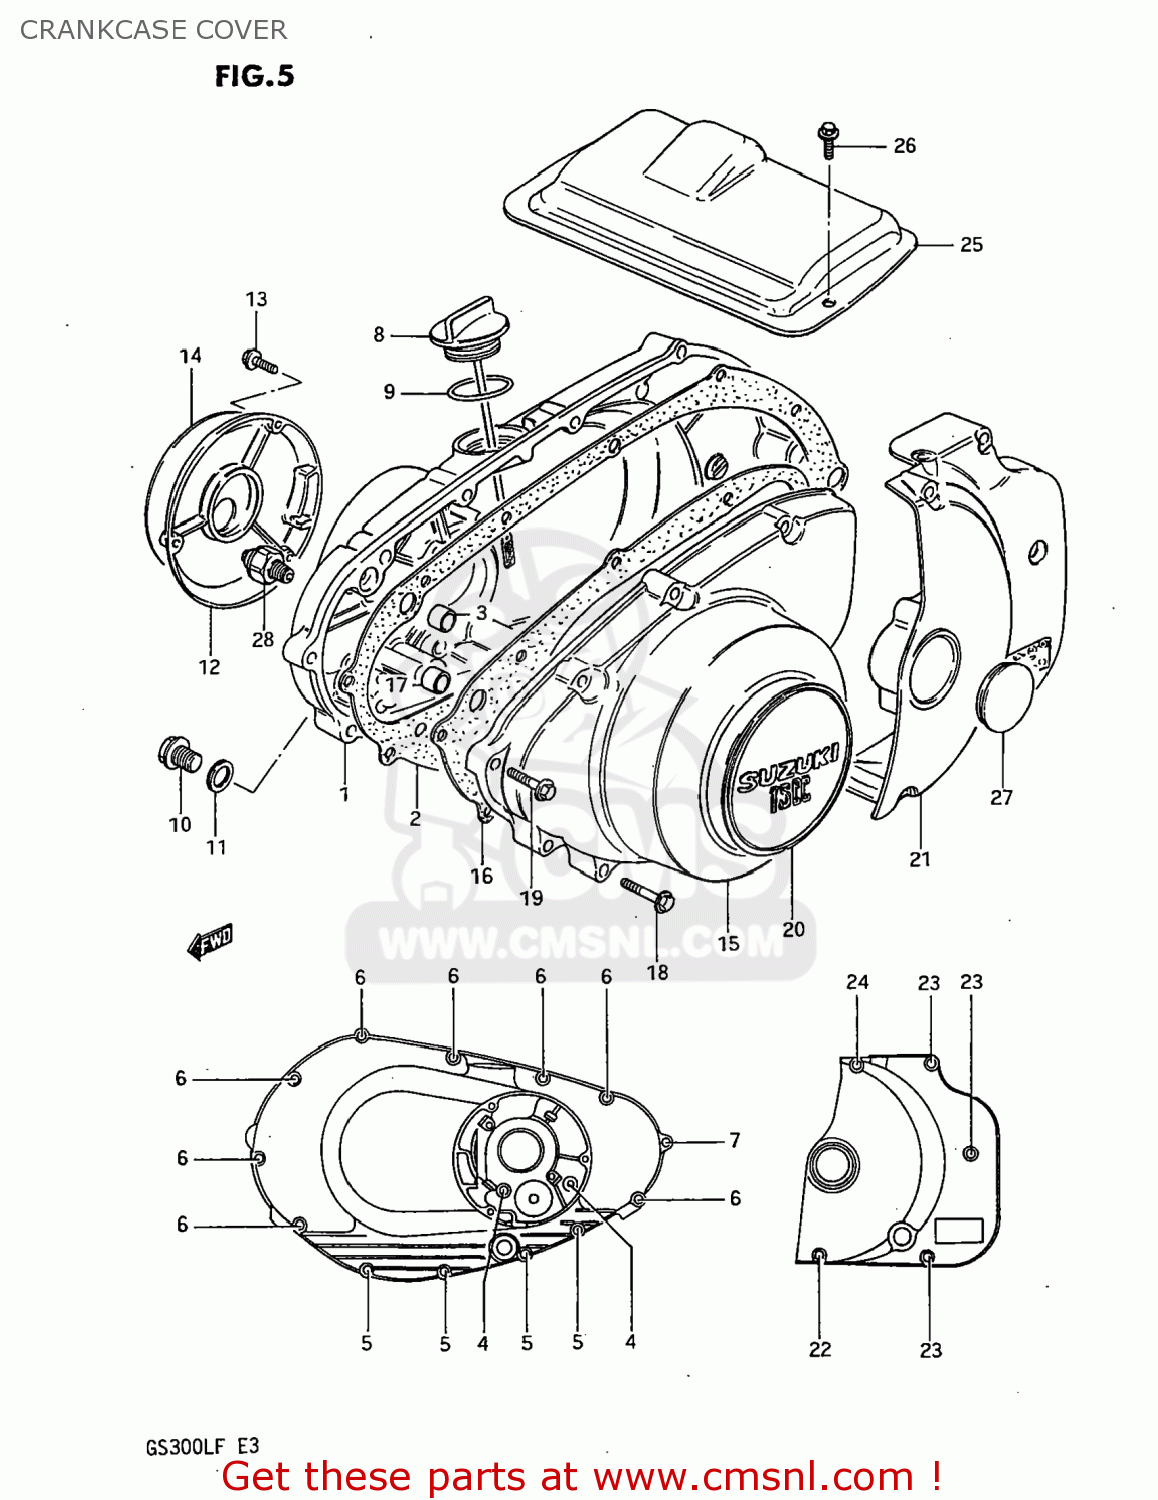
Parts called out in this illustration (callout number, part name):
1	COVER,CLUTCH
2	GASKET,CLUTCH COVER (MCA)
3	PIN
4	BOLT (6X50)
5	BOLT
6	BOLT (6X35)
7	BOLT
8	GAUGE,OIL LEVEL
9	O-RING
10	PLUG (14X12)
11	GASKET(14X19.2X2) (NAS)
12	COVER,CONTACT BREAKER
13	BOLT (5X20)
14	EMBLEM
15	COVER,MAGNETO
16	GASKET,MAGNETO COVER (MCA)
17	PIN
18	BOLT (6X30)
19	BOLT
20	EMBLEM
21	COVER,ENGINE SPROCKET
22	BOLT
23	BOLT (6X40)
24	BOLT (6X30)
25	COVER,STARTER MOTOR
26	BOLT
27	CAP(OD:36)
28	SWITCH ASSEMBLY
